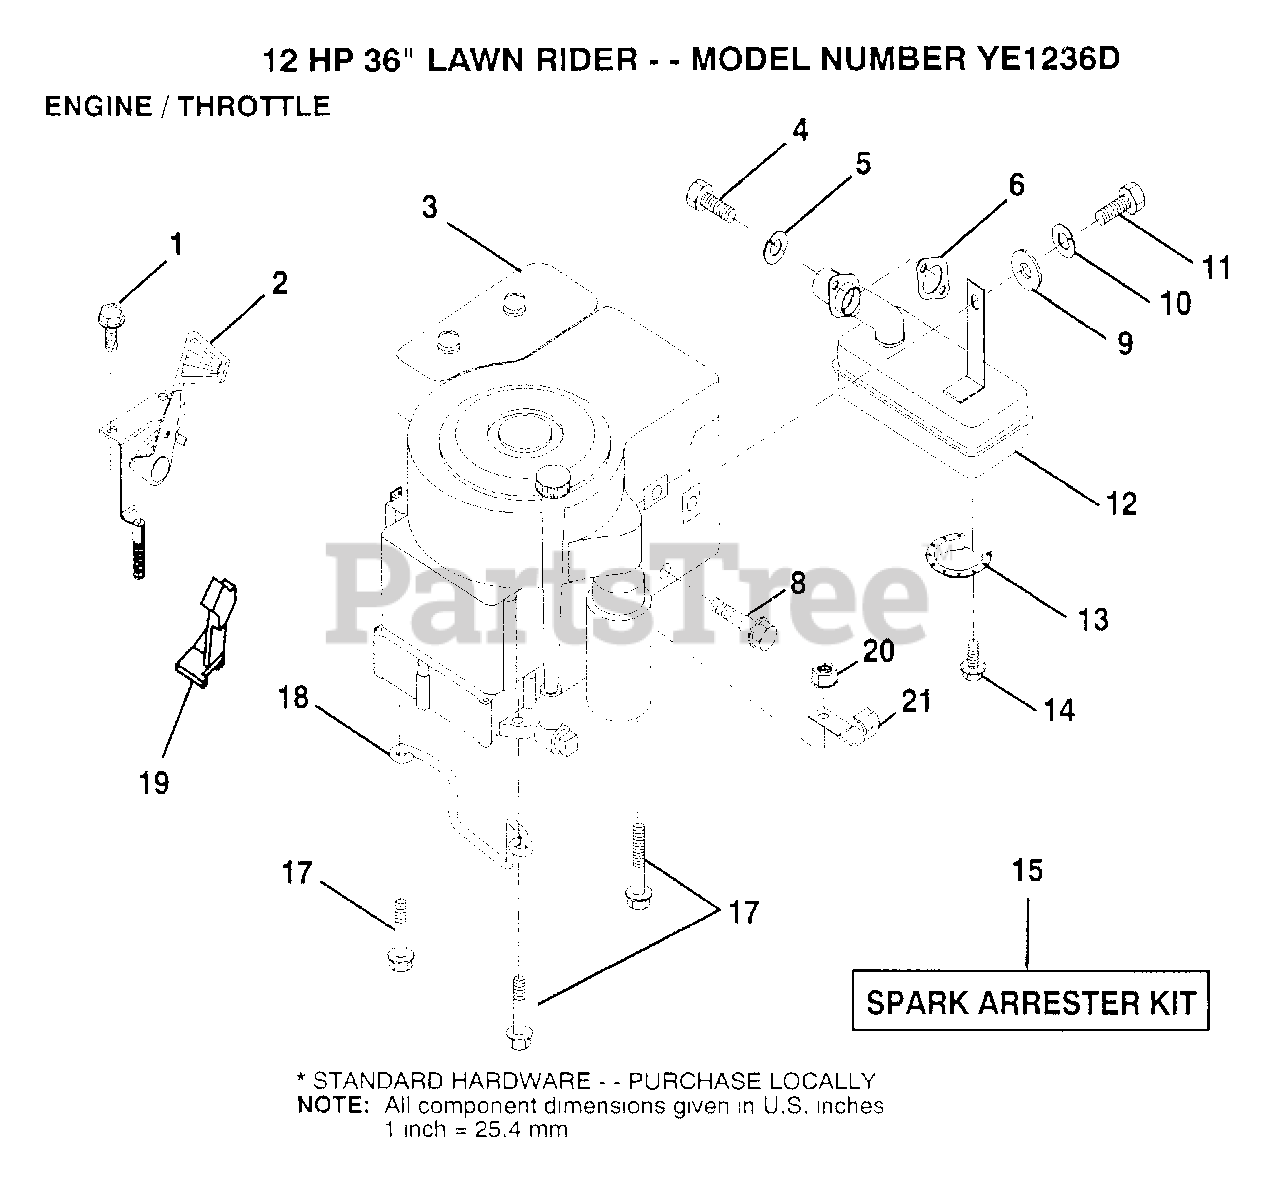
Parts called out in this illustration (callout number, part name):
1	SCREW
4	SCREW
5	LOCKWASHER
8	BOLT T
10	LOCKWASHER
13	DEFLECTOR.222573
17	SCREW LT
18	"KEEPER,DR BELT GR"
19	"STOP,DASH THROTT"
20	NUT
21	CLIP T
